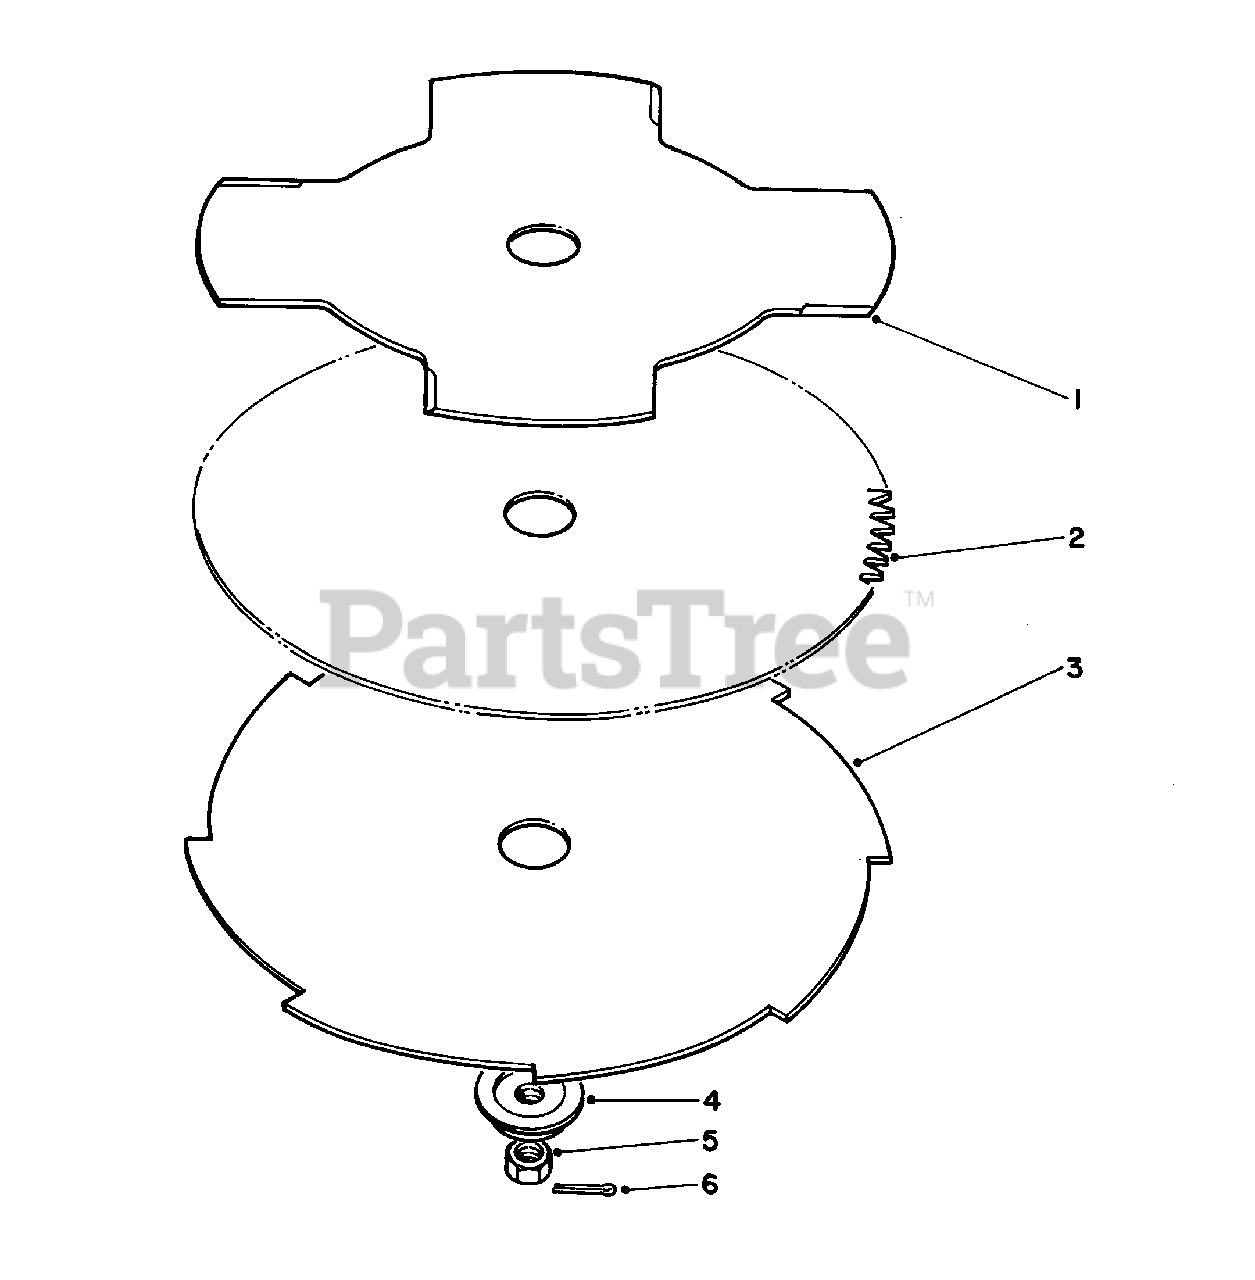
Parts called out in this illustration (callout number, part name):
1	8" Blade (4 T.)(optional)
2	8" Blade (80 T.)(optional)
3	8" Blade (8 T.)(optional)
4	Blade Adapter
6	Cotter Pin
